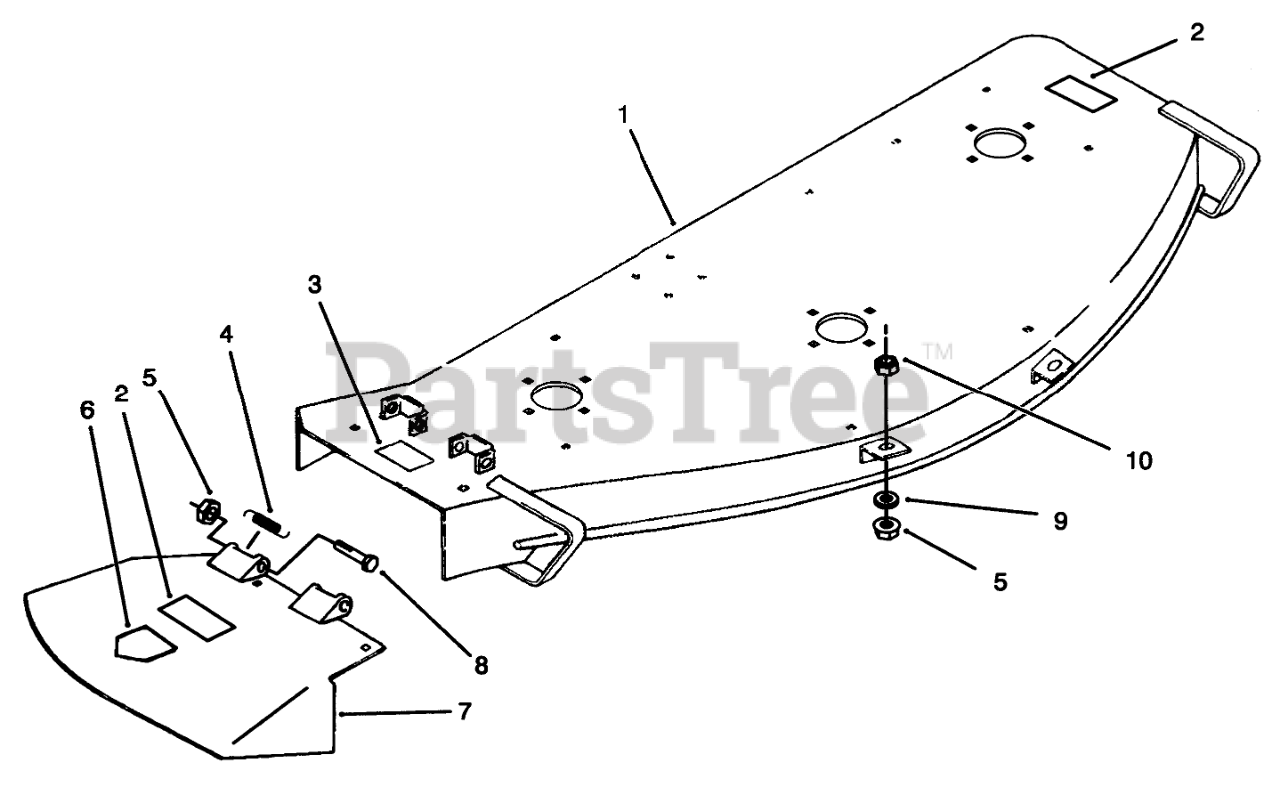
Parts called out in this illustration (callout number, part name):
1	50" DECK (TRK)
2	DECAL-DANGER, THROWN OBJECT
3	DECAL-DANGER
4	SPRING
5	NUT-LOCK, NI
8	SCREW-HH
9	WASHER-FLAT
10	NUT-FLANGE
